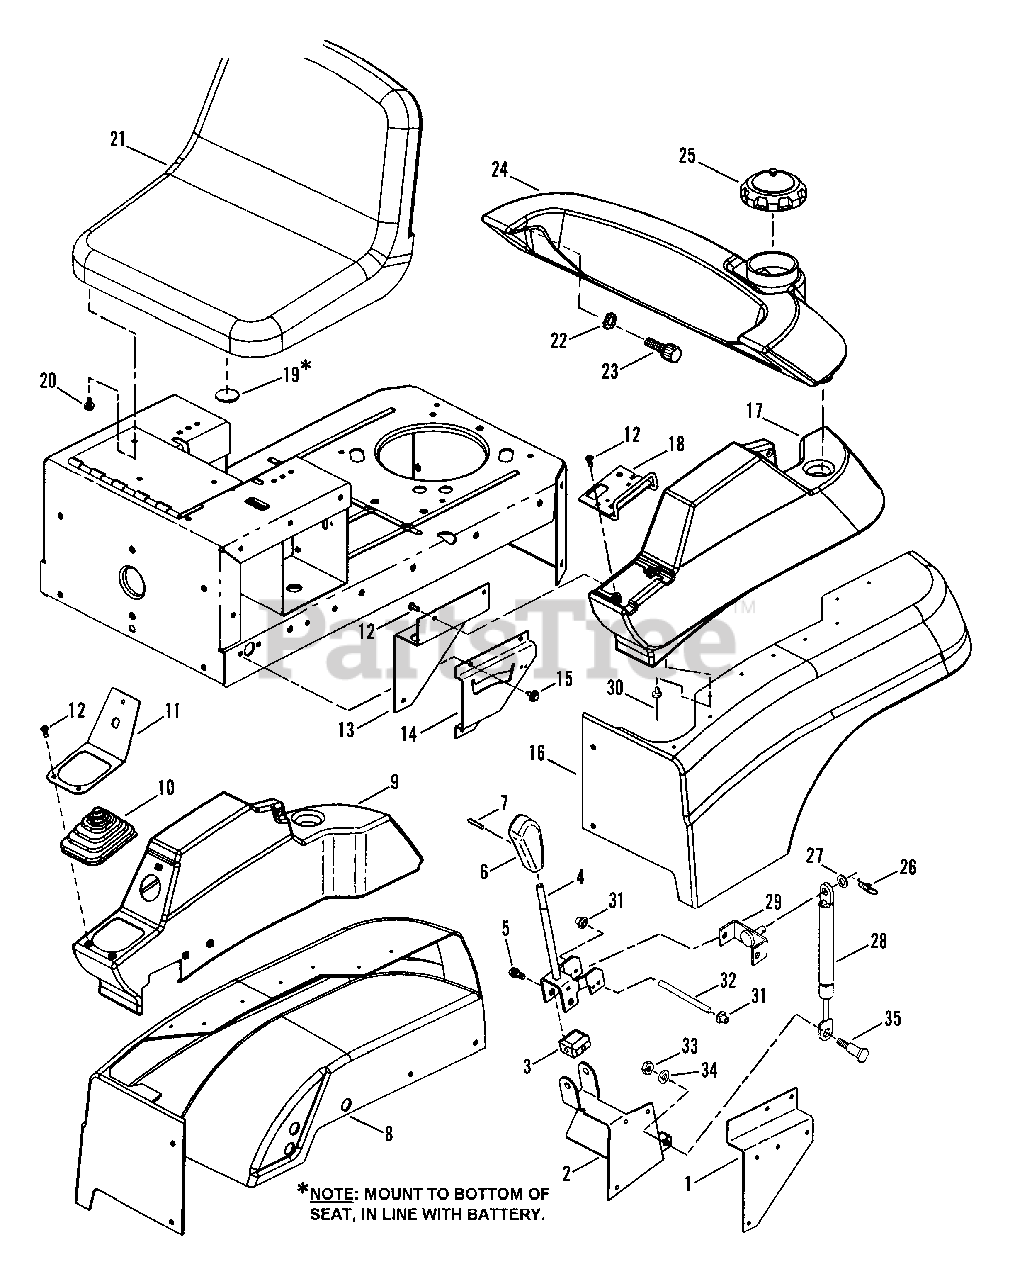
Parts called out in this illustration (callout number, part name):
1	BRACKET, R.H. Tank Support
2	BRACKET, Joystick
3	PIVOT, Joystick Control
4	HANDLE, Joystick Control
5	BOLT, 5/16-18 x 3/4" Shoulder
6	LEVER, Shift Handle
7	PIN, 3/16 x 3/4" Roll
8	FENDER, R.H. Rear Frame
9	FENDER, Upper R.H.
10	BOOT, Joystick, Rubber
11	BRACKET, Joystick/Key
12	SCREW, 1/4 x 5/8" Pan Head Self-Tap
13	BRACKET, L.H.Tank Support
14	BRACKET, Brake/Clutch Detent
15	SCREW, 1/4-20 x 5/8" Hex Washer Head, Self-Tapping
16	FENDER, L.H. Rear Frame
17	FENDER, Upper L.H.
18	GUARD, Throttle Control
19	BUMPER, Battery
20	SCREW, 5/16-18 x 1/2" Hex Washer Head, Machine
21	SEAT (All Models)
22	WASHER, 1/4" Internal/External Tooth
23	THUMBSCREW, 1/4-20 x 1-1/2"
24	ASSEMBLY, Fuel Tank
25	CAP, Fuel Tank (w/Gage & Screw Vent)
26	COTTER-PIN, 3/8 Self-Locking
27	WASHER, 11/32 x 11/16" Flat
28	CYLINDER, Joystick Control
29	BRACKET, Joystick Control
30	RIVET, 3/16" x 1" ,Dome Head, Aluminum
31	PUSH-NUT, 1/4"
32	PIN, Joystick
33	NUT, 5/16-18 Hex, Grade 5
34	WASHER, 21/64 Split Lock
35	BOLT, 5/16-18 x 1-1/8" Shoulder
